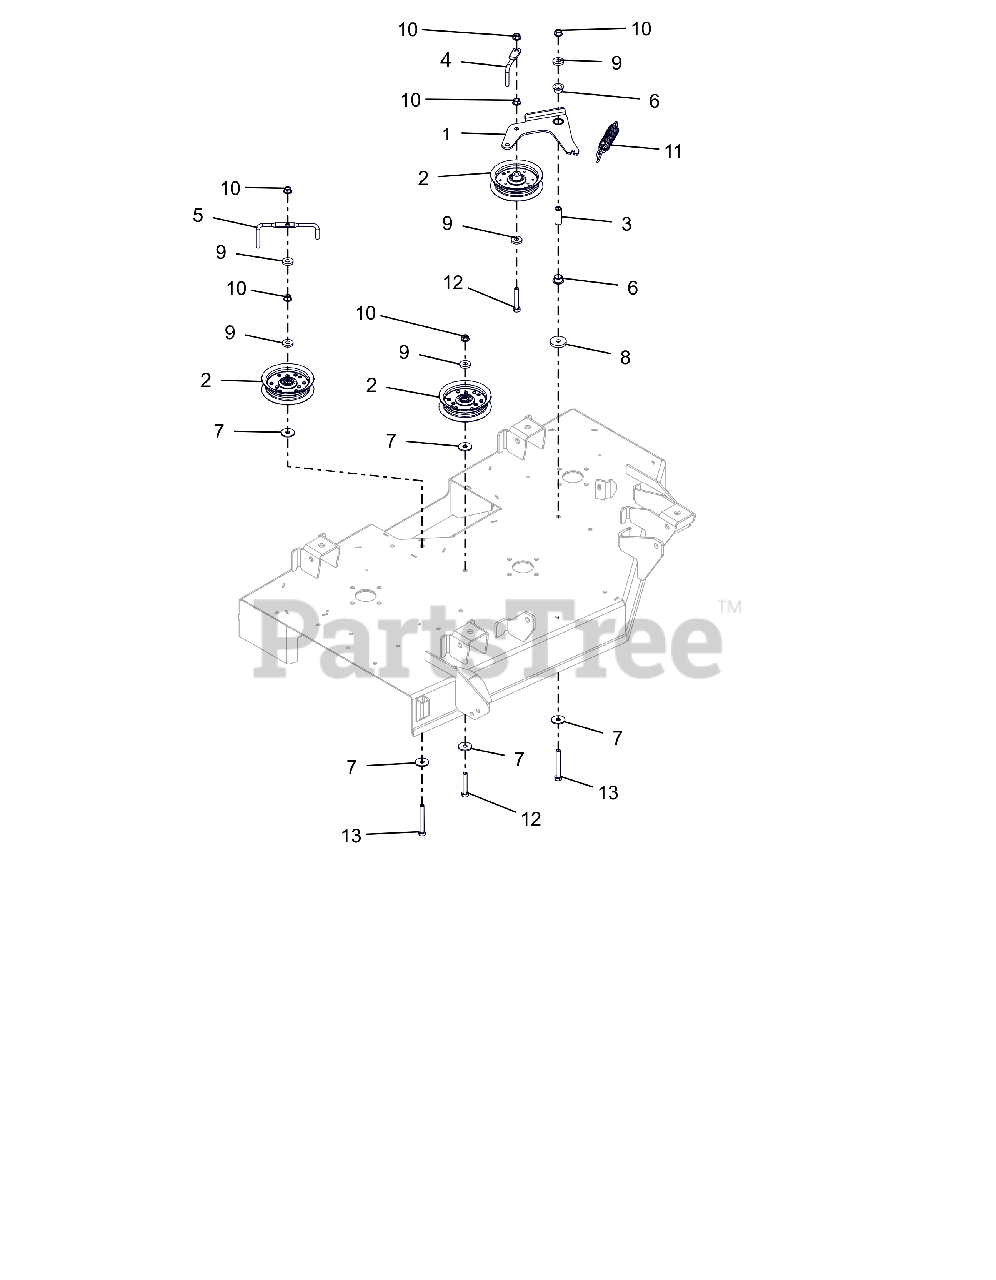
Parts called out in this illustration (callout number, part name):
1	WLDMT, IDLER ARM-42"
2	ASM, IDLER 4"
3	SPACER, .375IDX.625ODX1.66 PM
4	WIREFORM, BELT FINGER
5	WIREFORM, BELT FINGER
6	BSHG-FLG, .625X.750X.500X1.00
7	WSHR FL STL .406X1.25X.10ZC120
8	WSHR, FLT .406X1.50X.245 ZCC
9	WSHR, FLT .406X1.00X.188 ZCC
10	NUT-LK-TOP-FLG .38-16 ZC120
11	SG-TENS .135X.98X6.0 WLD 62
12	BLT,HEX .38-16X2.25 G5 ZCC
13	BLT, HEX .38-16X3.00F G5 ZCC
